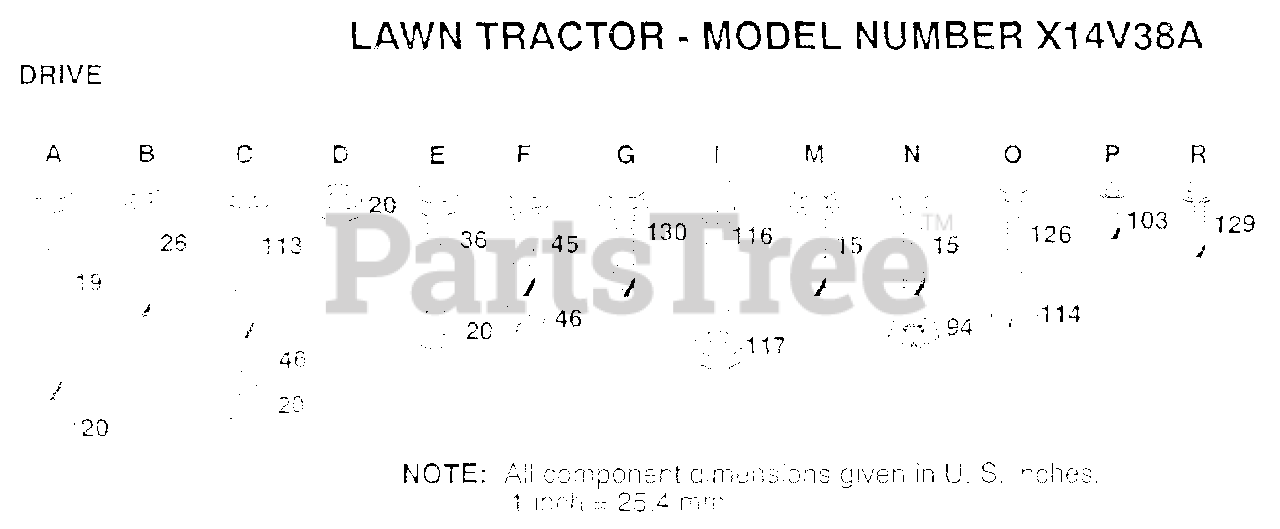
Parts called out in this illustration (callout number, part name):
15	SCREW LT
19	BOLT
26	SCREW
45	SCREW
46	WASHER
94	LOCKWASHER
113	BOLT
114	WASHER
116	BOLT
126	PAL NUT LT
